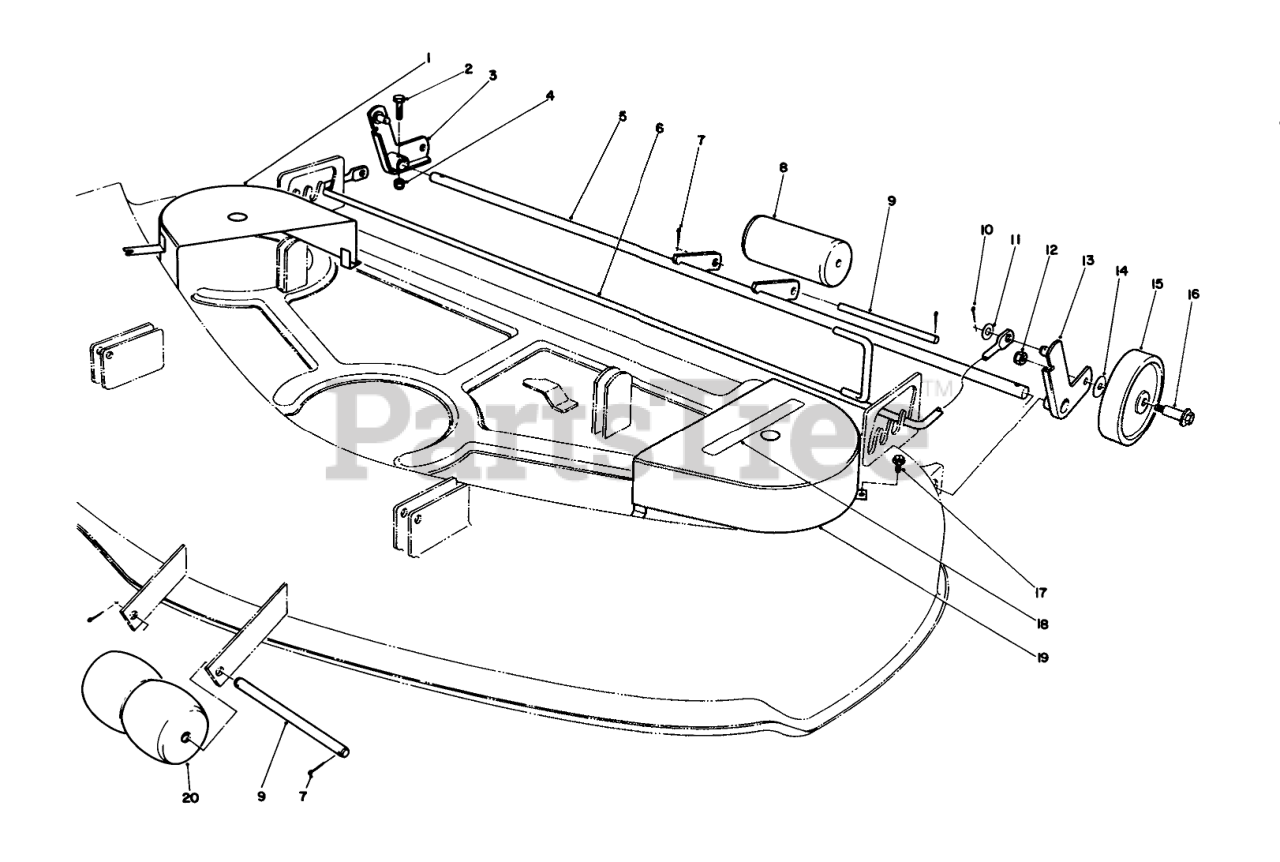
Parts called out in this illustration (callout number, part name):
1	Cover-Spindle R.H.
2	SCREW-HH
3	RH WHEEL BRKT WA B
4	NUT-LOCK, NI
6	Bracket
7	PIN-COTTER
8	ROLLER-DECK
9	ROLLER SHAFT
10	PIN-COTTER
11	WASHER-FLAT
12	NUT-LOCK, NI
13	LH WHEEL BRKT WA B
14	WASHER-THRUST
15	DECK WHEEL
16	BOLT-WHEEL
17	SCREW-HWHTF
18	DECAL-NO STEP
19	Cover-Spindle
20	ROLLER
